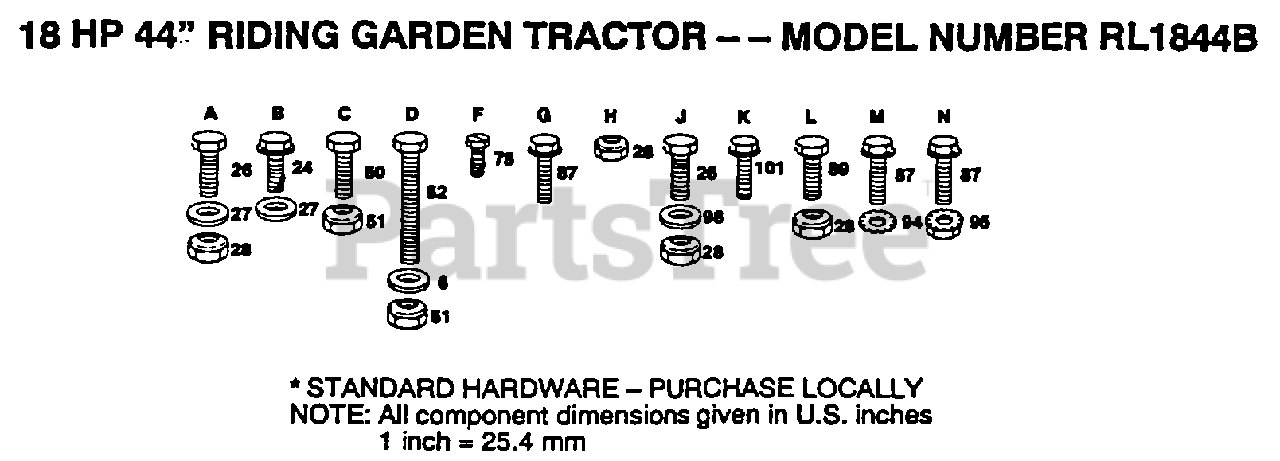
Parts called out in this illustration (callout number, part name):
6	WASHER
24	SCREW
26	BOLT
27	WASHER
50	BOLT
62	WASHER
76	VALVE CAP
87	SCREW LT
94	LOCKWASHER
96	NUT
98	WASHER
99	REAR BAFFLE T
101	SCREW
